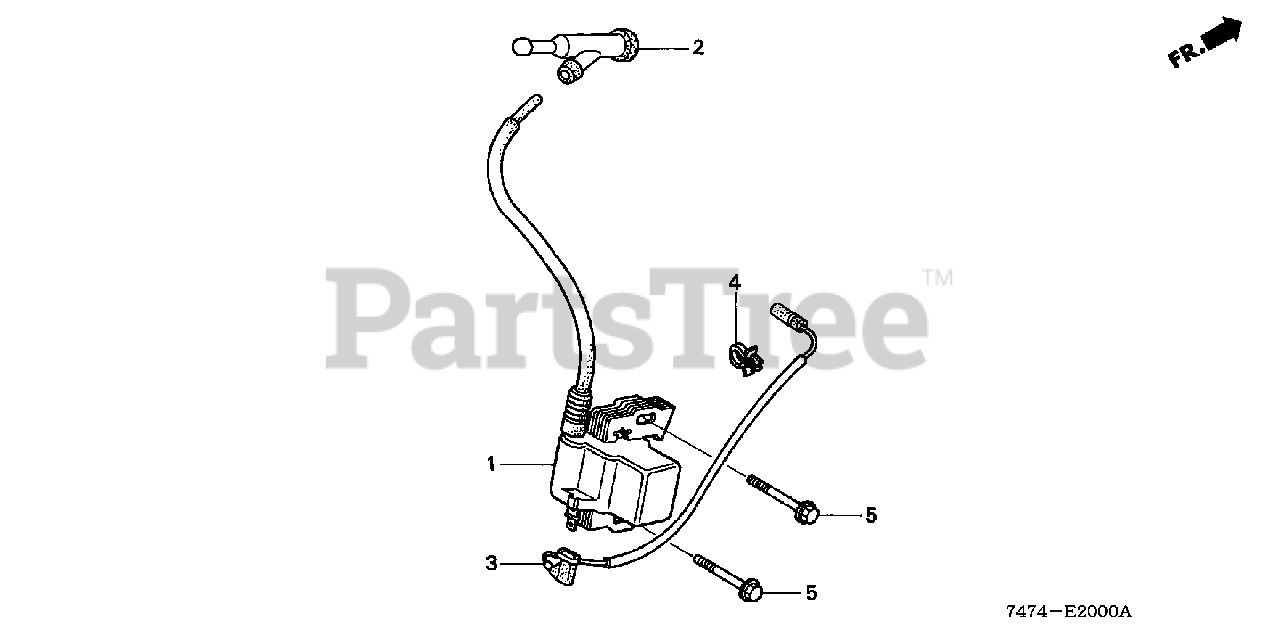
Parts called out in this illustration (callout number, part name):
1	COIL ASSY., IGNITION
2	CAP ASSY., NOISE SUPPRESSOR
3	WIRE, STOP SWITCH (230MM)
5	BOLT, FLANGE (6X25)
